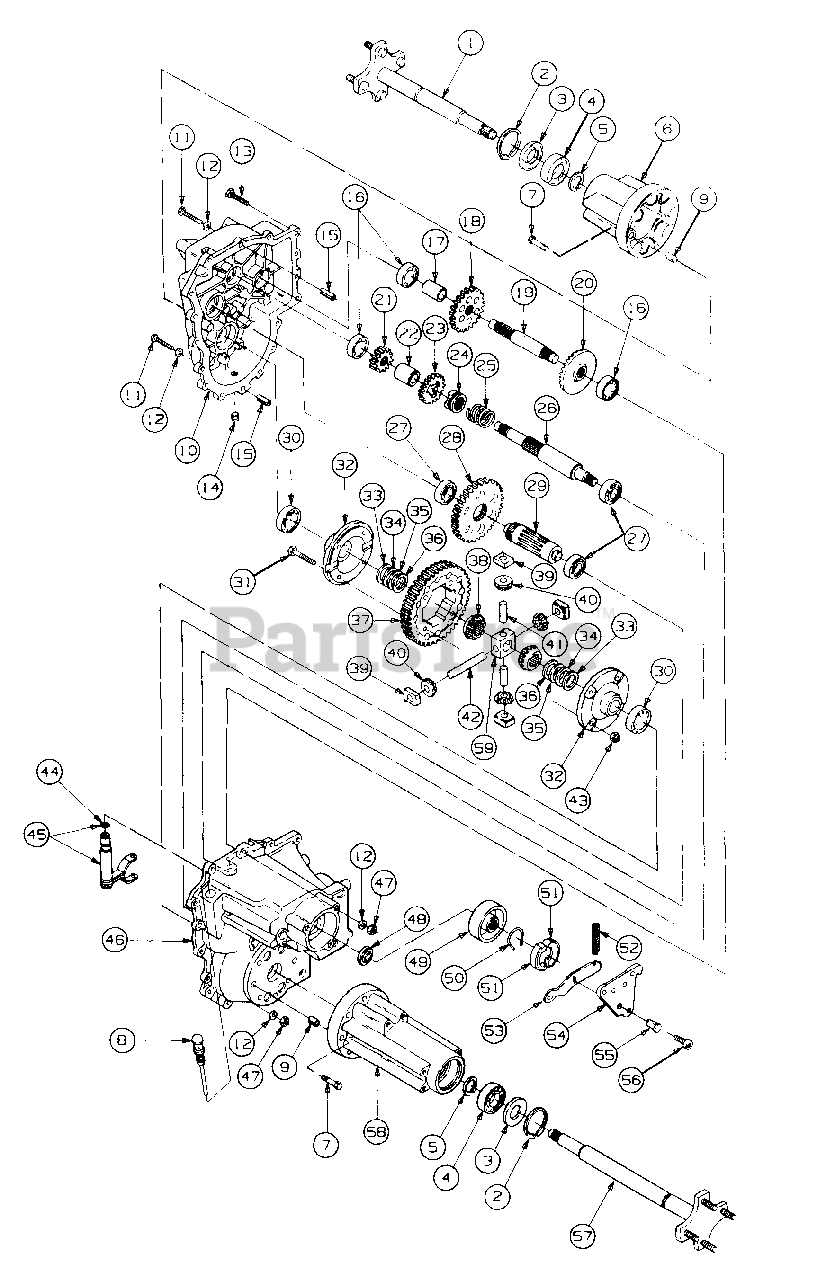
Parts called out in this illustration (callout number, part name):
1	Axle Assy, LH, 11.9" Lg
2	Ring, Inverted Retainer
3	Seal, Oil
4	Bearing
5	Ring, External Retaining
6	Housing, LH Axle
7	Screw, Hex L-Wash Tapp, 3/8-16 x 1.88
8	Dipstick, Oil
9	Bushing, Dowel
10	Housing, LH Differential
11	Screw, Hex Cap, 1/4-20 x 1.5
12	Washer, Flat, .25 x .62 x .052
13	Screw, Hex Wash Hd Tapp, 1/4-20 x 1.0
14	Plug, 1/2-14 NPTF
15	Pin, Slotted Spring, 7/16-1.0
16	Bearing, Ball
17	Spacer, .757 ID x 1.0 OD x 1.46
18	Gear, 27T Drive
19	Shaft, Drive
20	Gear, 36T Bevel
21	Gear, 16T Spur
22	Spacer, .885 ID x 1.125 OD x 1.4
23	Gear, 1ST Shift
24	Collar, Drive
25	Spring, Compression 1.015 ID x 1.6 Lg
26	Shaft, Shifter
27	Bearing, Ball, .787 x 1.85 x .551
28	Gear, 427 Spur
29	Shaft, 9T Output
30	Bearing, Ball.
31	Screw, Hex Cap, 3/8-24 x 2.0
32	Cover,Differential
33	Washer, Flat, 1.0 x 1.56 x .010 Thk
34	Washer, Flat, 1.0 x 1.56 x .015 Thk
35	Washer, Flat, 1.0 x 1.56 x .020 Thk
36	Washer, Flat, 1.0 x 1.56 x .040 Thk
37	Gear, 60T Bull
38	Gear, 14T Differential Side
39	Block, Differential Thrust
40	Gear, 10T Differential Pinion
41	Shaft, Cross
42	Shaft, Cross, .50 OD x 3.485 Lg
43	Nut, Hex Lock, 3/8-24
44	O-Ring, 3/8 ID x 1/2 OD
45	Yoke Assy, Shift
46	Housing, RH Differential
47	Nut, Hex Center Lock, 1/4-20
48	Seal, Shift Shaft
49	Drum, Brake
50	Spring, Brake
51	Shoe, Brake
52	Spring, Compression
53	Arm, Brake
54	Plate, Brake
55	Actuator, Brake Shoe
56	Screw, Low Hd Cap, 3/8-16 x .75
57	Axle Assy, RH, 15.6 Lg
58	Housing, Axle - RH
59	Block, Differential Pinion
